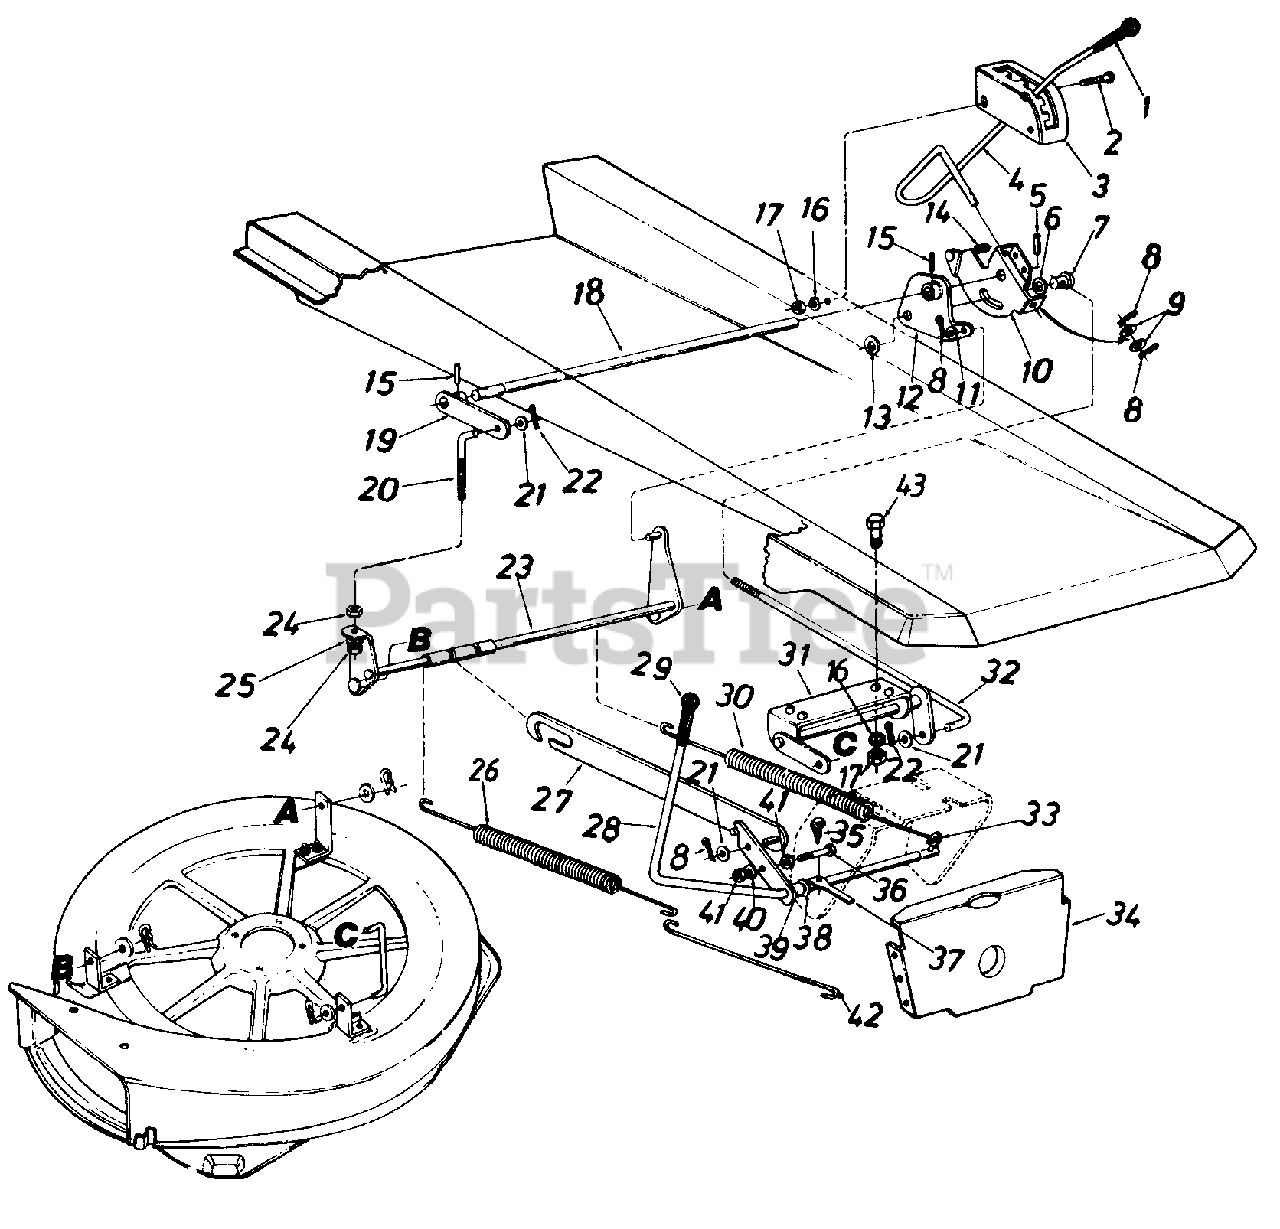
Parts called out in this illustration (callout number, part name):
2	Truss Mach. Scr. 5116-18 x .75" Lg.
5	Spring Pin Spir. 8/16" Dia. x 1.50" Lg.
6	Fl-Wash. .385" I.D. x 87" O.D.
7	Adj. Ferrule Deck Lift Handle
8	Cotter Pin 1/8" Dia. x 1 oon Lg.
9	Fl-Wash. .531" I.D. x.930" O.D.
10	Deck Lift Handle Retainer Ass'y.
11	Fl-Wash. .385" I.D. x 87" O.D.
12	Deck Lift Brkt. Ass'y.-L.H.
13	Fl-Wash. 635" l.D. x 1.04" O.D.
14	Compression Spring 60" Dia. x 1 on Lg.
15	Spring Pin Spir. 114" Dia. x 1.50" Lg.
16	L-Wash. 5116" l.D.
17	Hex Nut 5116-18 Thd.
18	Rear Hgt. Adj. Shaft
19	Deck Lift Brkt. Ass'y.-R.H.
20	Deck Adj. Scr. 318-16 Thd.
21	Fl-Wash. 385" l.D. x .87" O.D.
22	Intern. Cotter Pin 1/2" Dia.
23	Deck Link Ass'y.-Rear
24	Hex Nut 3/8-16 Thd.
25	L-Wash. 3/8" l.D.
26	Extension Spring 73" O.D. x 13.84" Lg.
27	Deck Drive Control Bracket
28	Blade Engagement Lever Ass'y.
30	Extension Spring 73" O.D. x 13.84" Lg.
31	Deck Lift Ass'y.-Front
32	Deck Lift Connecting Rod
33	Clevis Pin Special 250" Dia.
34	Pivot Bar Bracket
35	Hex TT-Tap Scr. 1/4-20 x .75" Lg.
36	Hex Bolt 5/16-18 x 1.50" Lg. (Grade 5)
37	Switch Actuator
38	Fl-Wash. 531" l.D. x 930" O.D.
39	Spacer.511" I.D. x 70" O.D. x.38" Lg.
40	L-Wash. 5/16" I.D.
41	Hex Nut 5/16-18 Thd.
43	Hex Bolt 5/16-18 x .75" Lg.
